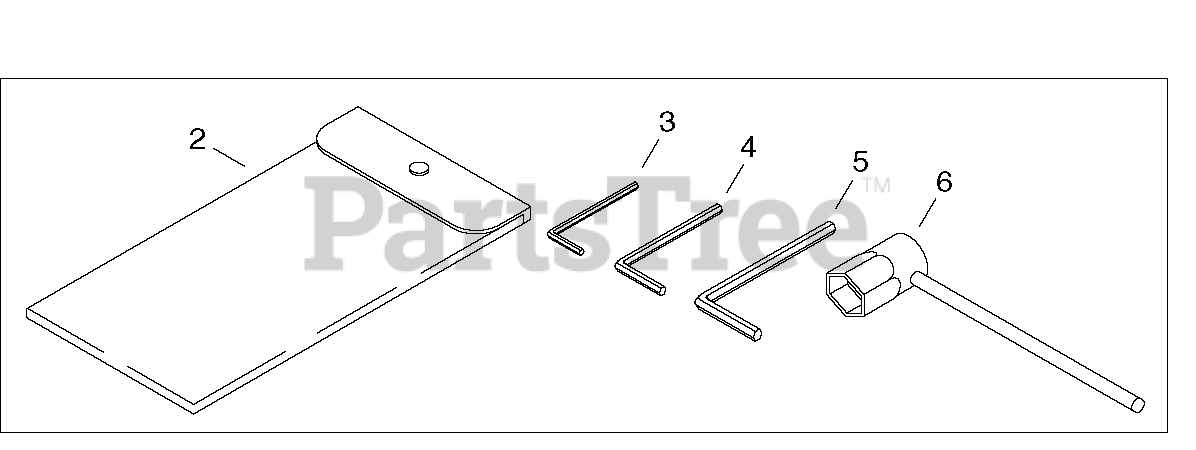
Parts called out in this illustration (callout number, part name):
1	TOOL KIT, SERVICE
2	BAG, TOOL
3	WRENCH, ALLEN 3 MM
4	WRENCH, ALLEN 4 MM
5	WRENCH, ALLEN 5 MM
6	T-WRENCH 19 MM
